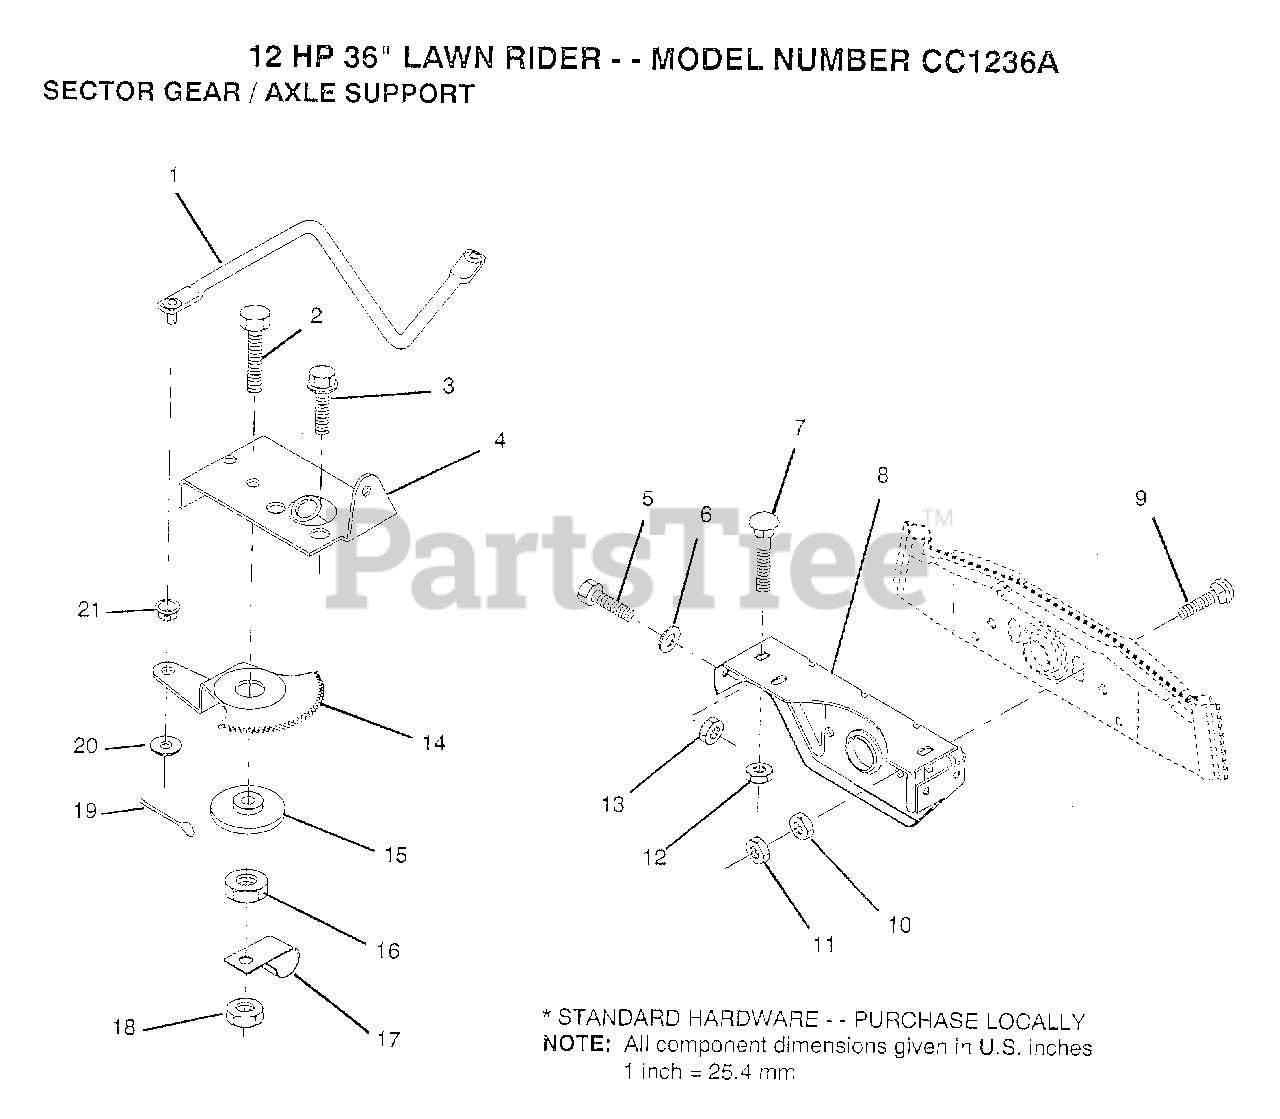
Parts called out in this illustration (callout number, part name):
2	"BOLT,HEX"
3	SCREW LT
4	"PLATE,STR SUPT"
5	BOLT
6	WASHER
7	BOLT
8	"SUPT,FRT AXLE"
9	BOLT
10	NUT.HEX.3/8-16UNC
11	LOCKNUT
14	GEAR SECTOR
15	BUSHING
16	NUT
17	CLIP INSULATOR
18	NUT LTV
19	COTTER PIN
20	WASHER
21	BUSHING.DRAGLINK
